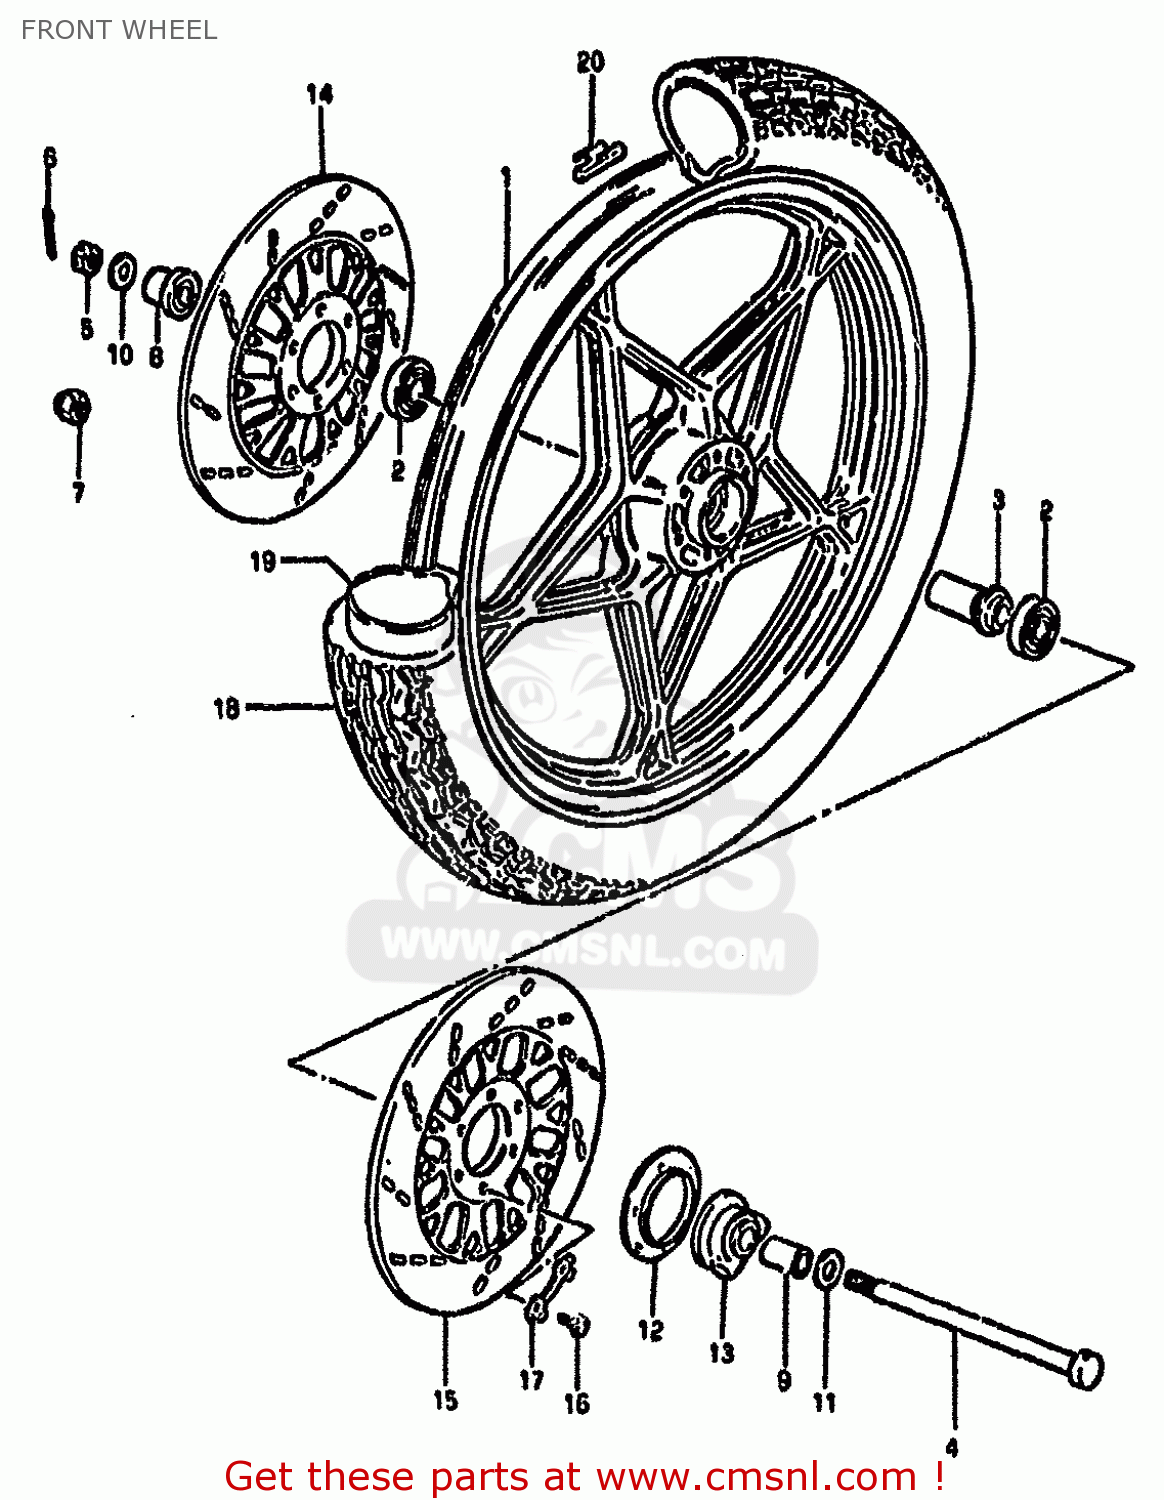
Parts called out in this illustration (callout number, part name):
1	WHEEL,FRONT (1.85-19)
2	BEARING
3	SPACER,FR HUB BEARING
4	AXLE,FRONT
5	NUT 12MM
6	COTTER PIN
7	NUT
8	SPACER,FR HUB BEARING,R
9	SPACER(15X22X30)
10	WASHER
11	WASHER
12	DUST SEAL,SPEEDOMETER GEAR BOX
13	BOX ASSEMBLY,SPEEDOMETER GEAR
14	DISC,BRAKE
15	DISC,BRAKE
16	BOLT(8X28)
17	WASHER
18	TIRE,FRONT
19	TUBE,INNER
20	BALANCER,WHEEL
